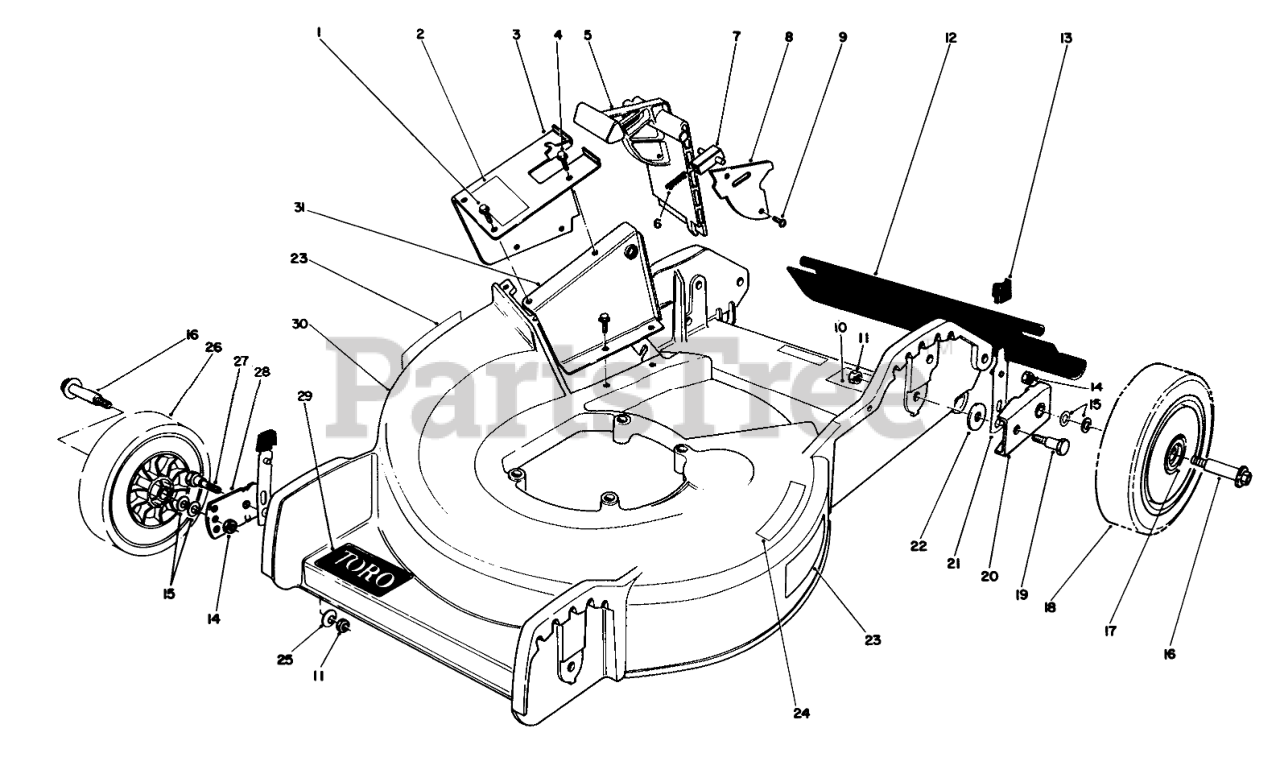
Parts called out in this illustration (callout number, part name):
1	SCREW
2	DECAL - DANGER
3	Tunnel-Outer (Incl. Ref. #2)
4	SCREW
5	Door-Mulching
6	SPRING-COMPRESSION, LATCH
7	Door Latch
8	DOOR COVER
10	Decal-Noise
11	NUT-LOCK, NI
12	SHIELD - TRAILING
13	KNOB-ARM
14	Nut
15	WASHER
16	BOLT-WHEEL
17	BUSHING
18	Wheel & Tire Assembly (Incl. Ref. #17)
19	PIVOT SCREW
20	PIVOT ARM ASM
21	SPRING ARM ASM
22	PIVOT WASHER
23	Decal Danger
24	DECAL - STEP PAD INT'L
25	WASHER-BELLEVILLE
26	Wheel & Tire Assembly (Incl. Ref. #17)
27	5/16-18 PIVOT SCREW
28	PIVOT ARM ASSY
29	DECAL
30	Housing (Incl. Ref. #23)
31	Tunnel-Inner
